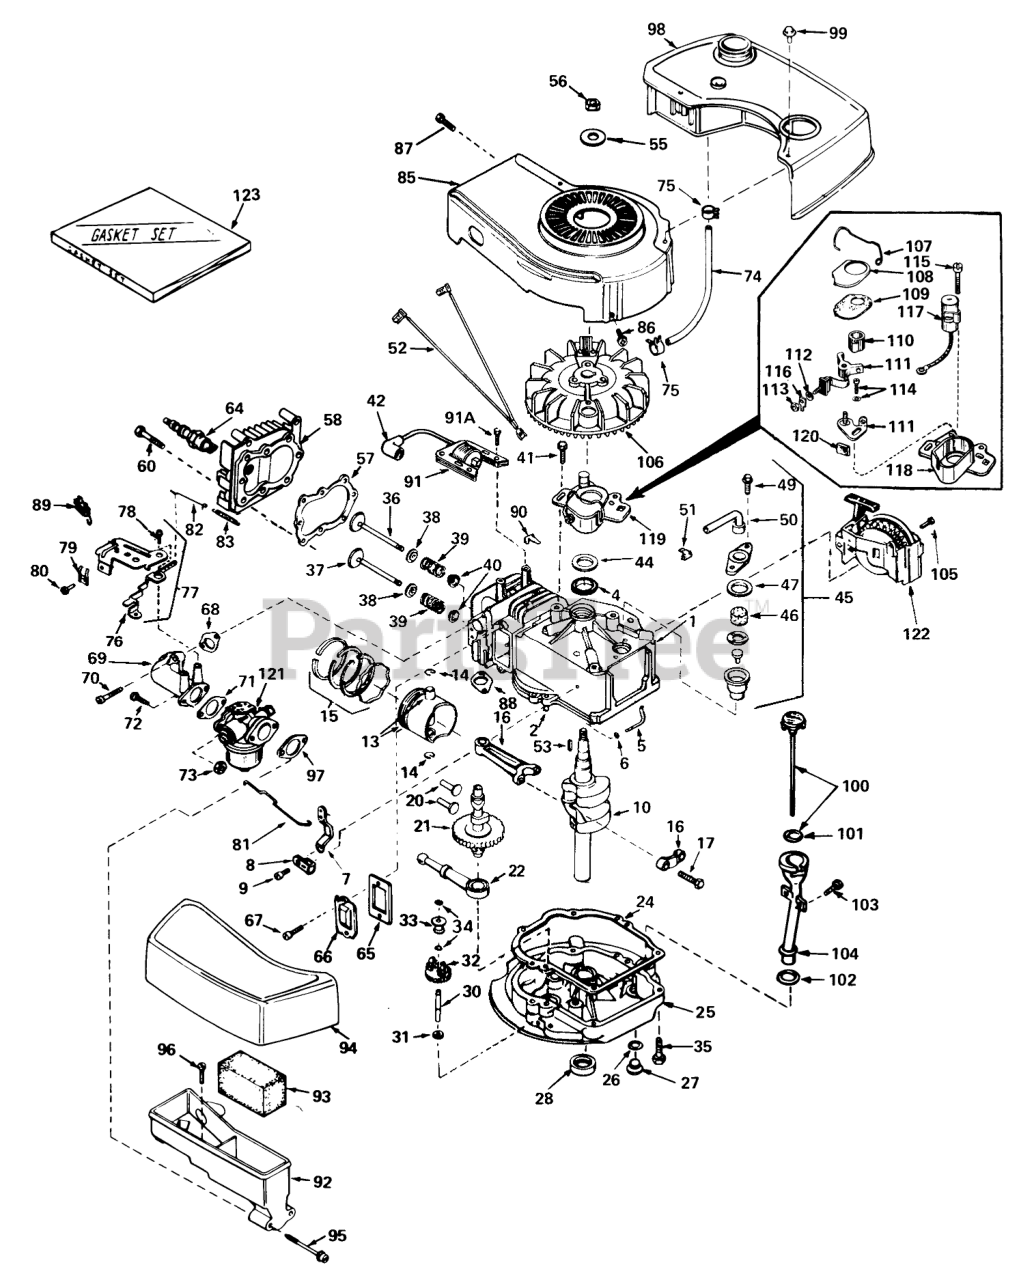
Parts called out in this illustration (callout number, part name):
1	Cylinder Assy. (Incl. #2, 4 & 105)
2	Pin-Dowel
4	Seal-Oil
5	Rod, Governor (Incl. #6)
6	Washer-Flat
7	Governor Lever
8	Clamp-Lever, Governor
9	Screw
10	Crankshaft
13	Piston, Pin & Ring Assy. (Incl. #14 & 15)(Std.)
13	Piston, Pin & Ring Assy. (Incl. #14 & 15)(.010 oversize)
13	Piston, Pin & Ring Assy. (Incl. #14 & 15)(.020 oversize)
14	Ring-Retaining, Piston Pin
15	Ring Set Piston (Std.)
15	Ring Set Piston (.010 Oversize)
15	Ring Set Piston (.020 Oversize)
16	Rod Assy., Connecting (Incl. #17)
17	Bolt-Rod, Connecting
20	Lifter-Valve
21	Camshaft(Mech.Comp. Release)
22	Oil Pump ASM
24	Gasket, Mounting
25	Flange Assy., Mounting (Incl. #26 thru 30)
26	Gasket-Oil Drain
27	Plug Oil Drain
28	Seal Oil
30	Shaft-Governor
31	Washer-Flat
32	Gear Assy., Governor (Incl. #31)
33	Spool-Governor
34	Ring-Retaining
35	Screw (1/4-20 x 1-1/4)
36	Valve, Intake (Std.)(Incl. #38, 39 & 40)
36	Valve, Intake (1/32" oversize)(Incl. #38, 39 & 40)
37	Valve, Exhaust (Std.)(Incl. #38, 39 & 40)
37	Valve, Exhaust (1/32" oversize)(Incl. #38, 39 & 40)
38	Cap-Upper Valve Spring
39	Spring-Valve
40	Cap-Valve, Spring
42	Cover-Spark Plug
44	Gasket Stator
45	Breather Assy. (Incl. #46, 47, 49, 50 & 51)
46	Element-Breather
47	Gasket-Breather
49	Screw, Hex Hd. w/Conical
50	Tube, Breaker
51	Clip, Breather
52	Wire Ground
53	682488 LB GRASS HI-
55	Washer-Belleville
56	Nut-Flywheel
57	63573 GIL 42 SNWTHW
58	Head-Cylinder
60	Screw (5/16-18x1-1/2)
64	Plug, Spark (J17LM or equiv.)
64	Plug, Spark (Champion RCJ-8)
65	Gasket-Breather
66	Cover-Valve
68	Gasket, Intake
69	Pipe, Intake
70	Screw (1/4-20 x 1)
71	Gasket-Carburetor
72	Screw (1/4-28 x 7/8)
73	Nut and Lock Washer (1/4-28)
74	Line-Fuel
75	Clamp-Line, Fuel
76	Lever Control
77	Control Assy . Speed (Incl. #77, 78 & 89)
78	Screw, Hex Washer Hd Shoulder Self-Tap
79	Conduit
80	Screw (10-32 x 3/8)
81	Link-Throttle
82	Link Governor Spring
83	Spring Governor
85	Housing, Blower
86	Screw
87	Screw (10-24 x 9/16)
88	Gasket Exhaust
89	Terminal
90	Clip-Wire
91	Lamination
91A	Screw
92	Body Air Cleaner
93	Filer, Air
94	Cove, Air Cleaner
95	Screw Fil Hd.
96	Screw, Hex Hd.
97	Gasket-Air Cleaner
98	Tank, Fuel
99	Screw (10-32 x 35/64)
100	Dipstick, OiI (Incl. #101)(Twist Lock)
103	Screw (10-32 x 1/2)
104	Tube-Oil Fill
105	Screw (1/2-20x5/8)
106	FIywheel
107	Spring Breaker Box
108	Cover-Dust
109	Gasket-Dust Cover
110	Cam-Breaker
111	Breaker Assy.
114	Breaker Screw
115	Condenser Screw
116	Terminal, Ground
117	Condenser
118	Stator Plate
119	Stator Assy. (Incl. #107, 111 thru 118 & 120)
120	Felt,Cam Wiper
121	Carburetor (Incl. #71)
122	Starter-Sidemount
123	53024/VAR.16HP O/P
